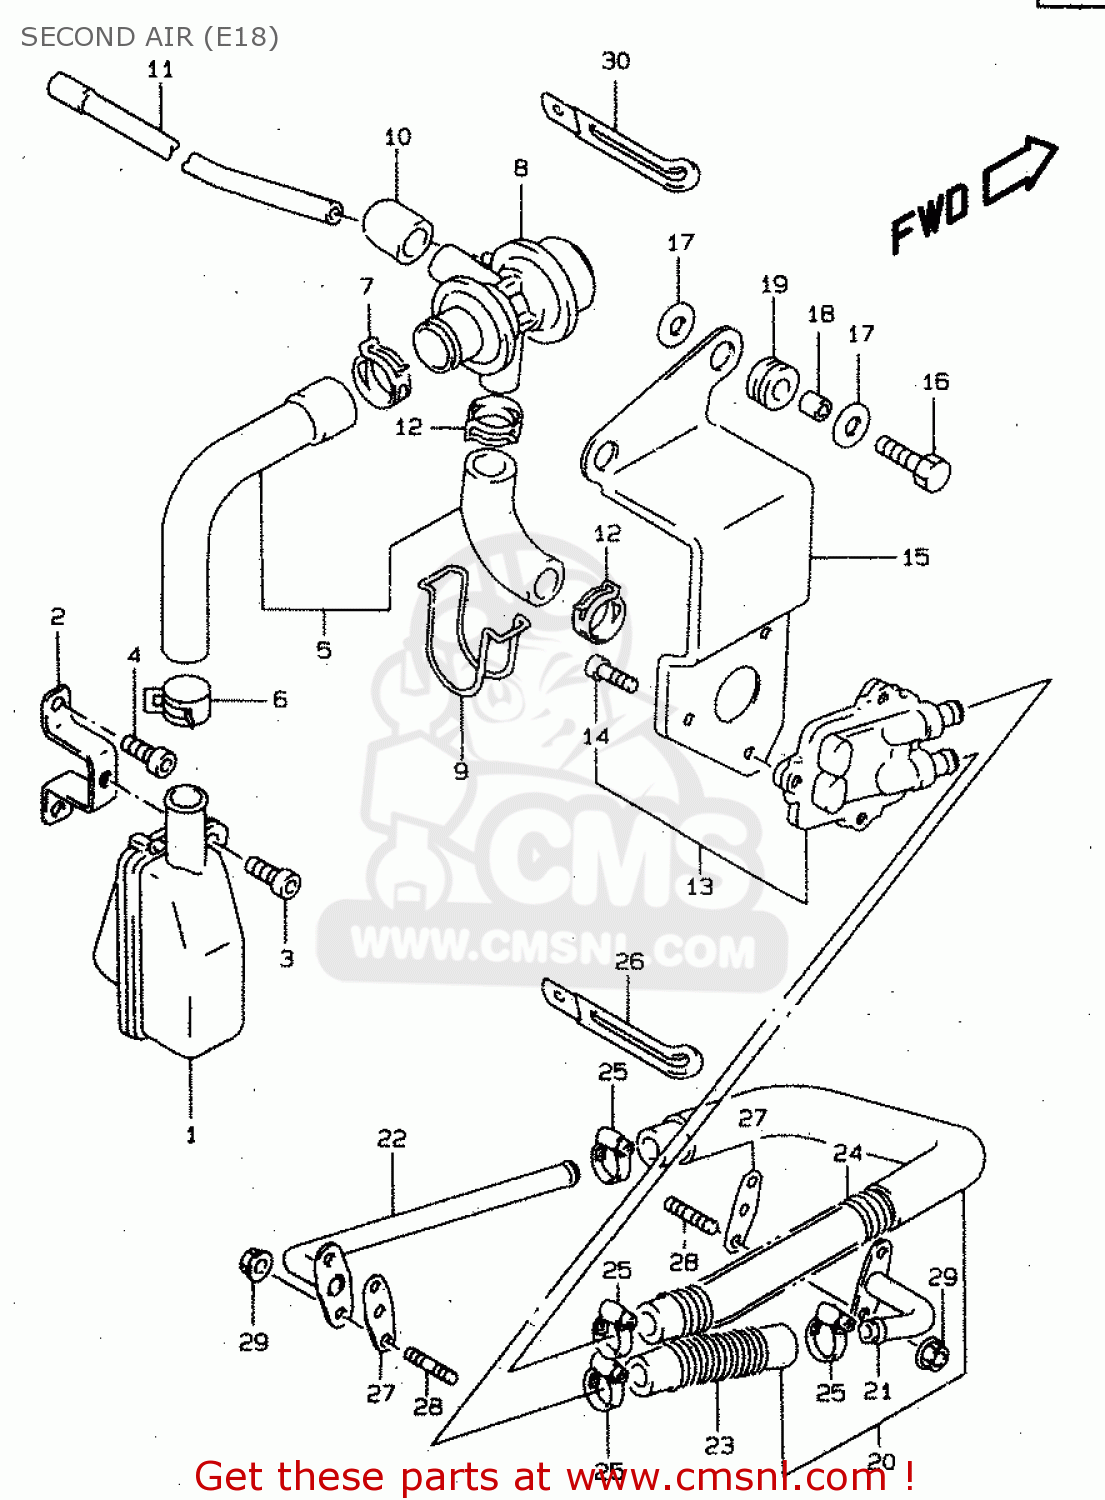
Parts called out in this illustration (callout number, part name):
1	CLEANER ASSY,AIR NO.2
2	BRACKET,2ND AIR CLEANER
3	BOLT
4	BOLT
5	HOSE SET,2ND AIR NO.2
6	CLIP
7	CLIP,SECOND AIR HOSE
8	VALVE ASSY,AIR SWITCHING
9	CLAMP,SWITCHING VALVE
10	CAP,SWITCHING VALVE
11	HOSE(4.5X8.5X600)
12	CLIP
13	VALVE ASSY,2ND AIR REED
14	BOLT
15	BRACKET, 2ND AIR VALVE
16	BOLT
17	WASHER(6.5X20X1.6)
18	SPACER(6.5X10X10)
19	CUSHION
20	HOSE SET, 2ND AIR
21	PIPE,2ND AIR FR
22	PIPE,2ND AIR RR
23	SPRING, FRONT HOSE
24	SPRING, REAR HOSE
25	CLAMP
26	CLAMP(L:80)
27	GASKET,SECOND AIR PIPE (N (NAS)
28	STUD 6X16
29	NUT
30	CLAMP(L:80)
